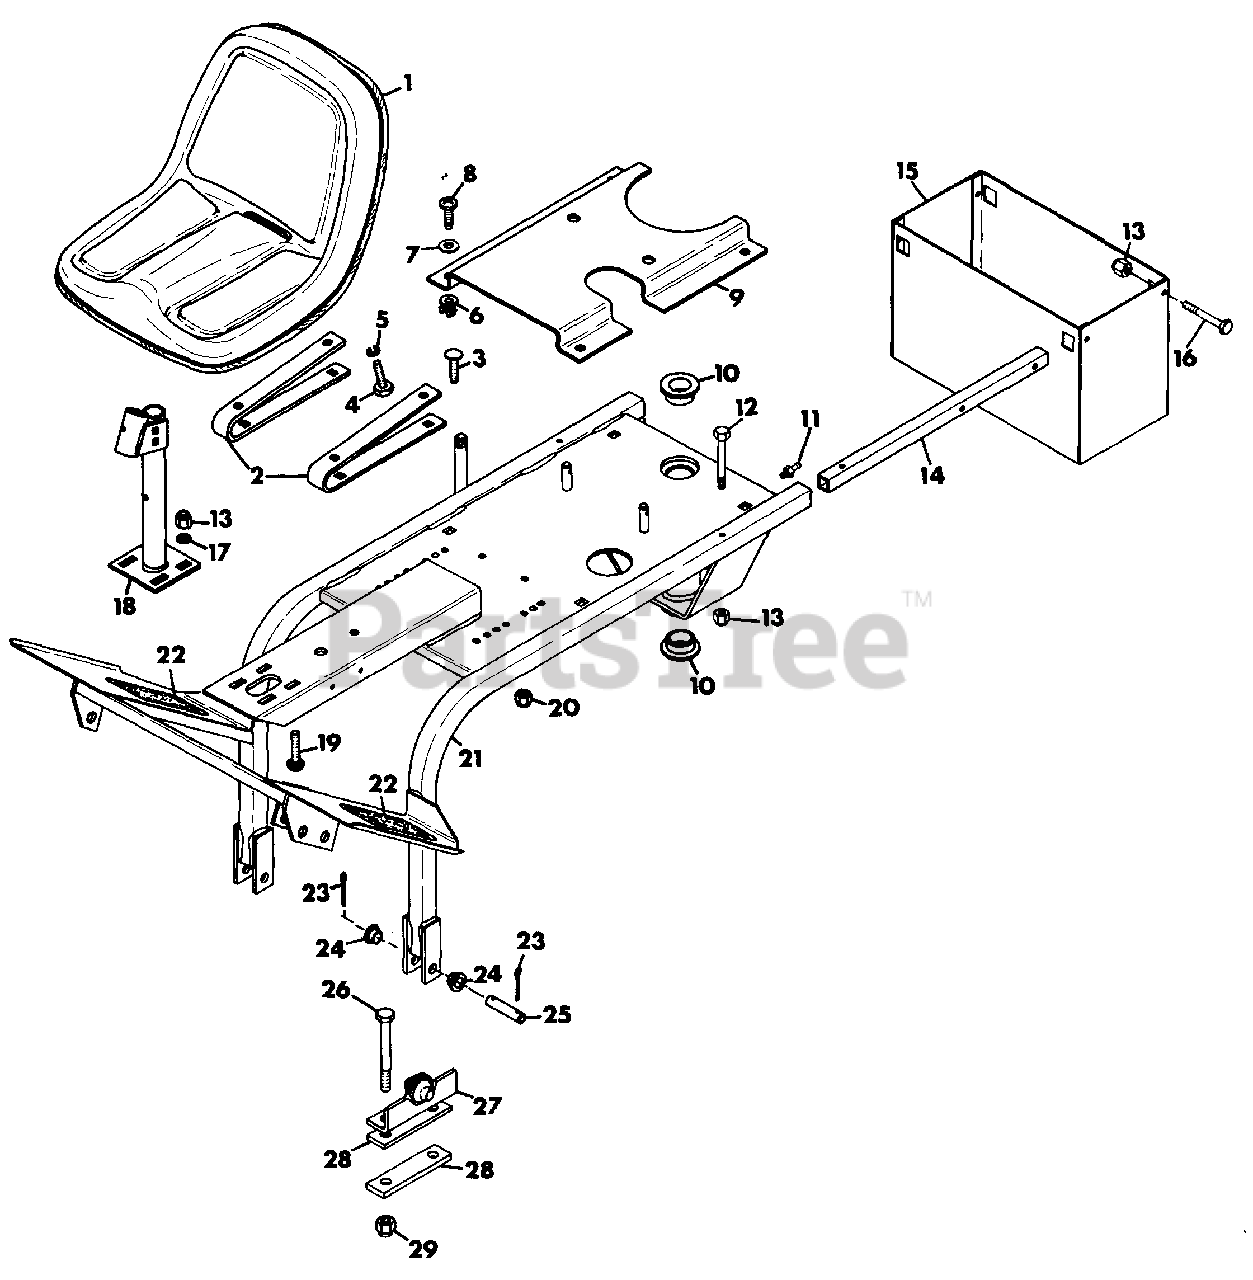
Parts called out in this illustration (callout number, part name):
1	ASSEMBLY, VALVE STEM
2	SEAL, WHEEL
3	BEARING, CONE
4	BEARING, CUP
5	RIM, REAR
6	TIRE, 16X7.50-8
7	RIM, PRO MASTER
8	TIRE, 20X10.00-10
9	STUD, WHEEL
10	WHEEL, REAR PRO MASTER
11	WHEEL, FRONT PRO MASTER
